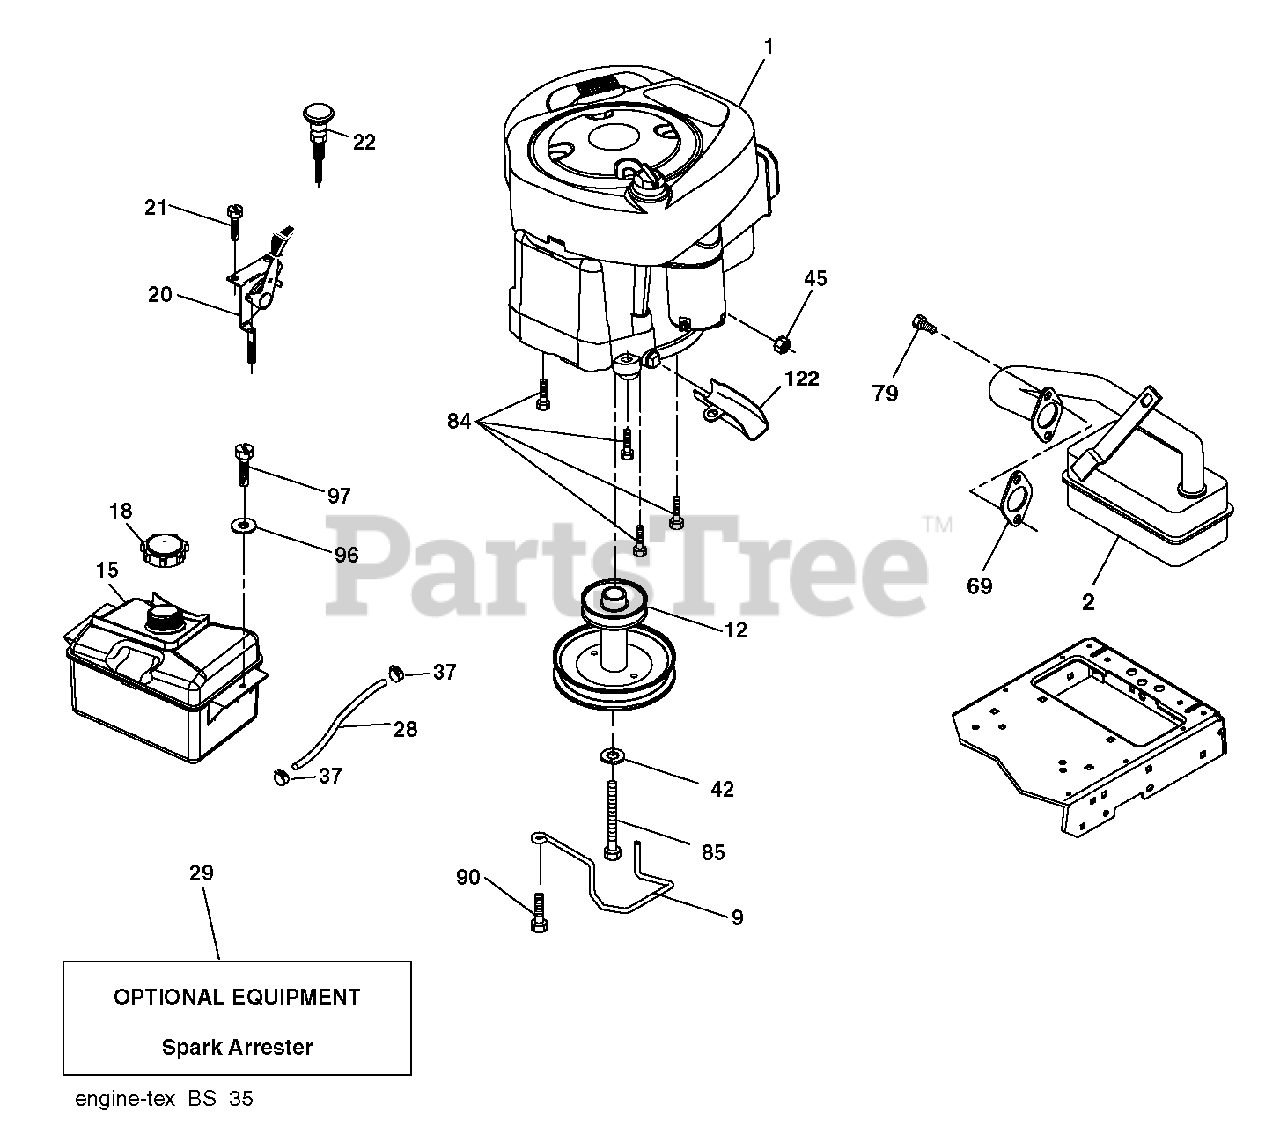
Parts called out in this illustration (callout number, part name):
9	KEEPER.BELT.ENGINE.4.2
12	PULLY ENGINE
15	TANK FUEL FRT 1.5 GAL
18	CAP ASM.FUEL.2.25"FR.
20	CONTROL.THCK.COBRA.BS
21	SCREW.#10 X 0.750.BOS THREAD
22	CONTROL.CHOKE.ERGO.1CYL.30".YE
29	ARRESTER SPARK (OPTIONAL)
42	LOCKWASHER
45	NUT
69	REPL BY 532 27 22-93
79	SCREW.SOCKET HD.5/16-1
85	BOLT HEX 7/16-20X4-1/4"
90	SCREW 3/8-16X1
97	SCREW HEXWSHR 1/4-20X3/4
122	EXTENSION DRAIN OIL
